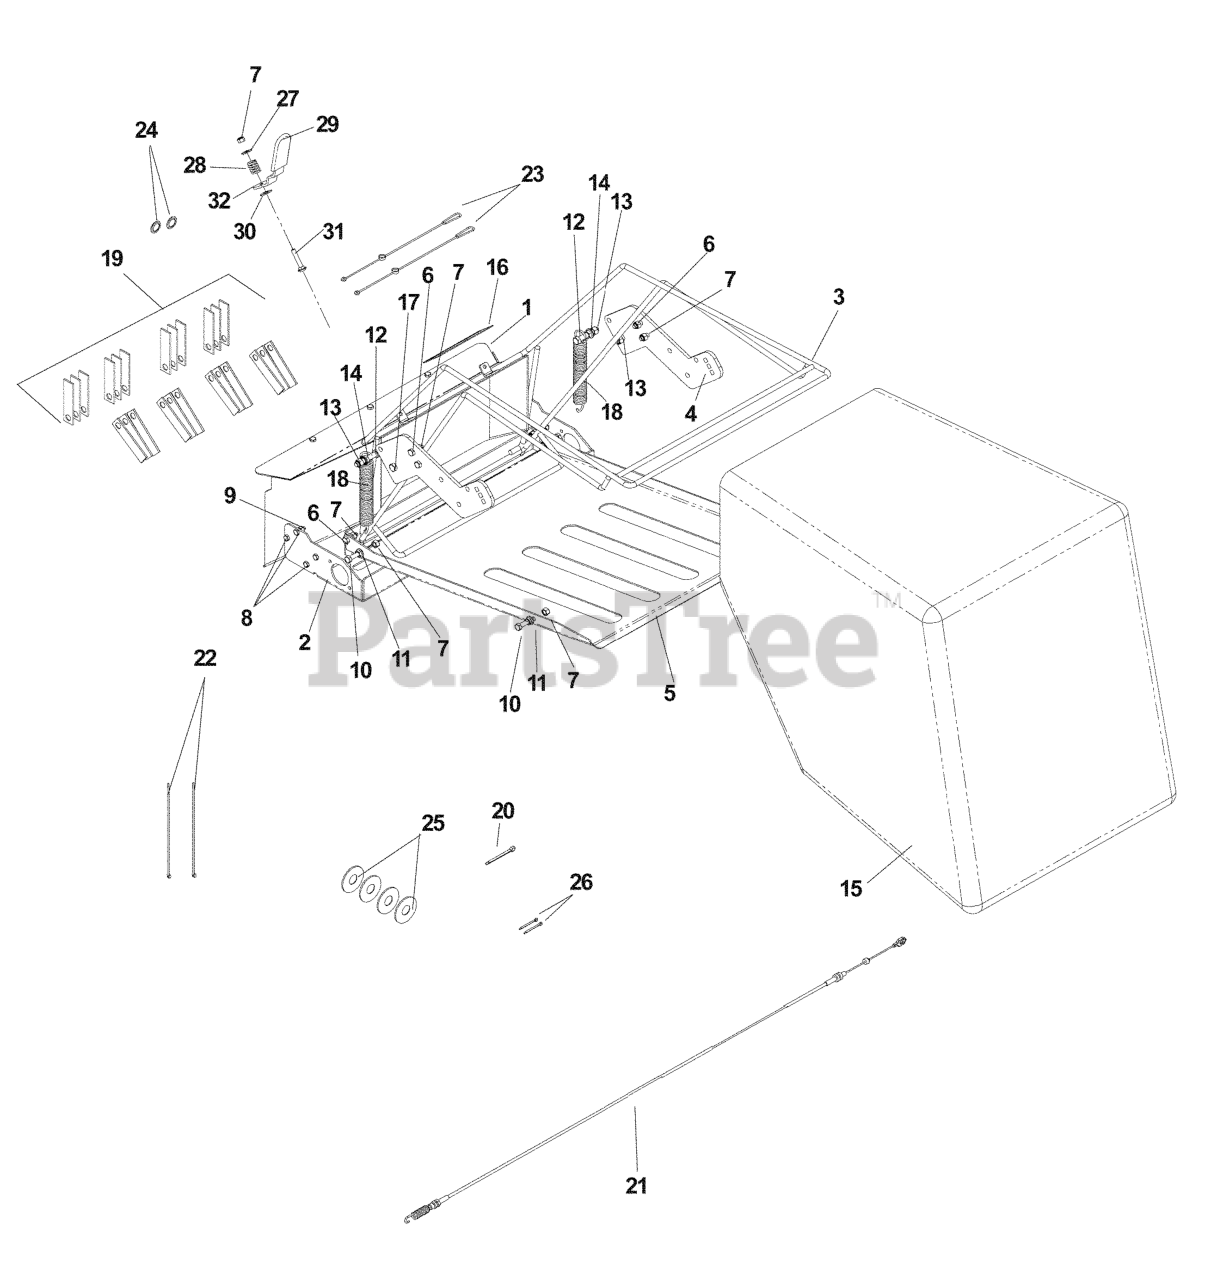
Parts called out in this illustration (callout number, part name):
1	CHUTE
2	BAGGER TRAY
3	BAG FRAME, BLACK
4	EXTENDER GREY
5	SAFETY DOOR ORANGE
6	HCS 5/16C X 1
7	NUT 5/16 NYLOC
8	HCS 1/4C X 3/4 HCS
9	NUT.1/4-20.HEX.NYLOC.ZD
10	HCS 5/16C X 1 3/4
11	NUT 5/16C WHIZ
12	HCS 3/8C X 2
13	NUT 3/8-16 NYLOC
14	NUT 3/8C WHIZ
15	CATCHER BAG
16	DECAL, WARNING
17	HCS 3/8-16X1.GRD.5.ZD
18	SPRING BAGGER
19	BLADE SET, 56 BLADES
20	COTTER PIN
21	CABLE 46.5" POWER RAKE
22	TIE, PLASTIC
24	RETAINING RING
25	WASHER
26	COTTER PIN
27	WASHER 5/16 FLAT
28	COMPRESSION SPRING
30	WASHER 3/8 FLAT
31	RHSNB 5/16-18X1 3/4
